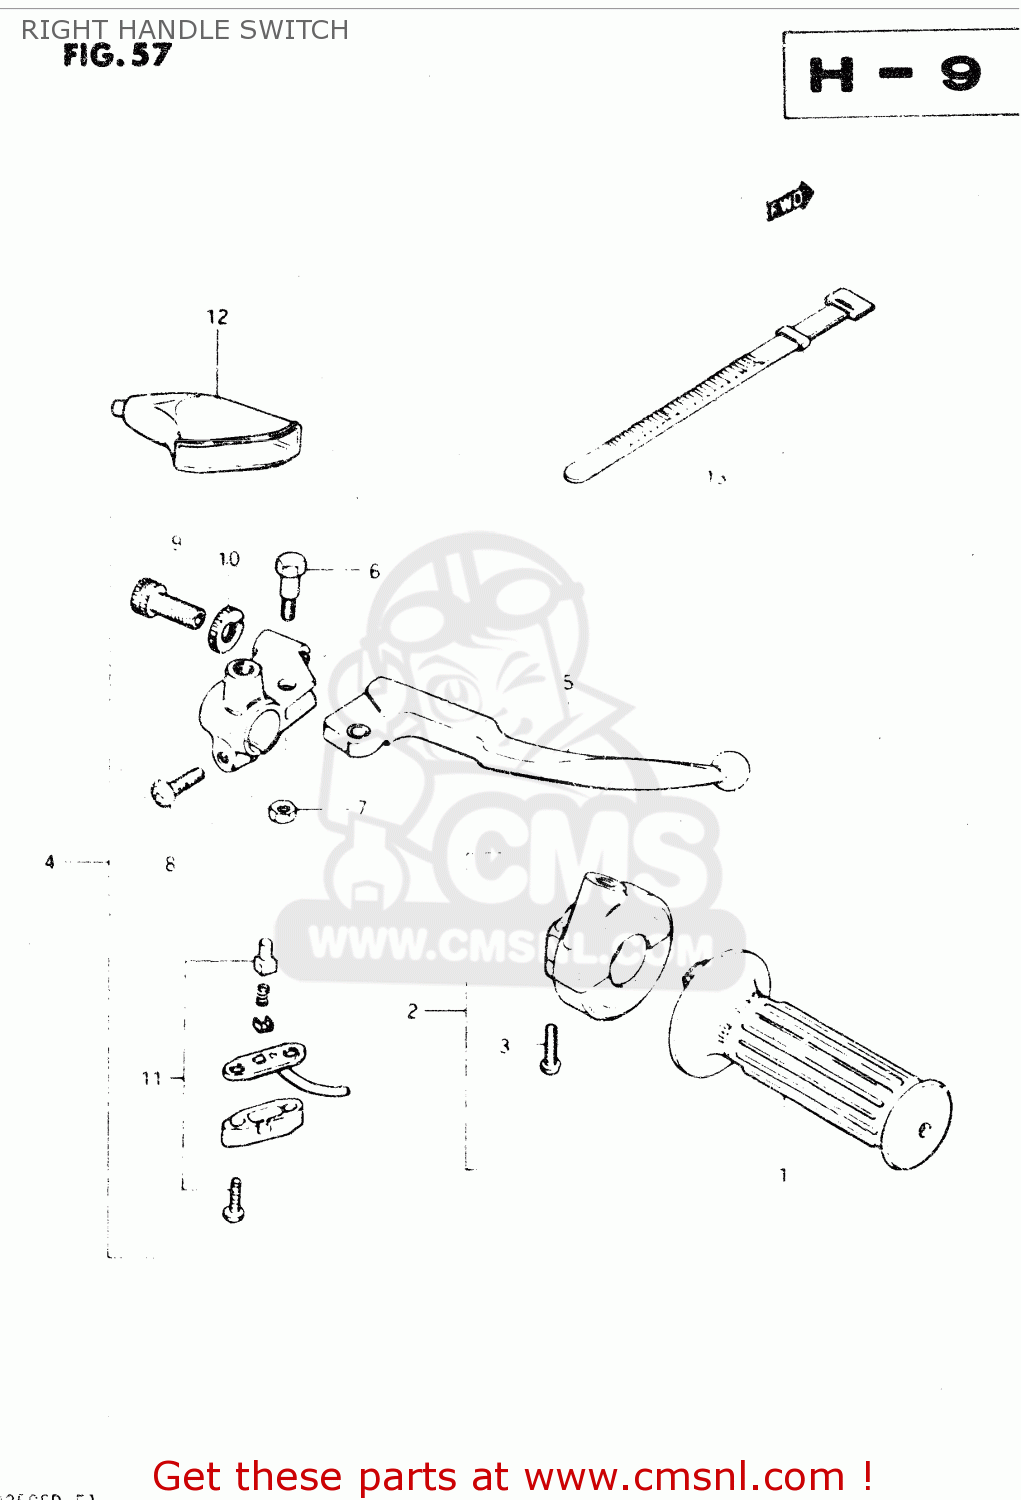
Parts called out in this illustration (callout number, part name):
1	GRIP,THROTTLE
2	CASE ASSY,THROTTLE
3	SCREW 5X20
4	LEVER ASSEMBLY,BRAKE
5	LEVER,BRAKE
6	BOLT,LEVER
7	NUT 6MM
8	SCREW
9	ADJUSTER,CABLE
10	NUT,CABLE ADJUSTER
11	SWITCH ASSEMBLY
12	COVER,CLUTCH LEVER
13	CLAMP(L:120)
